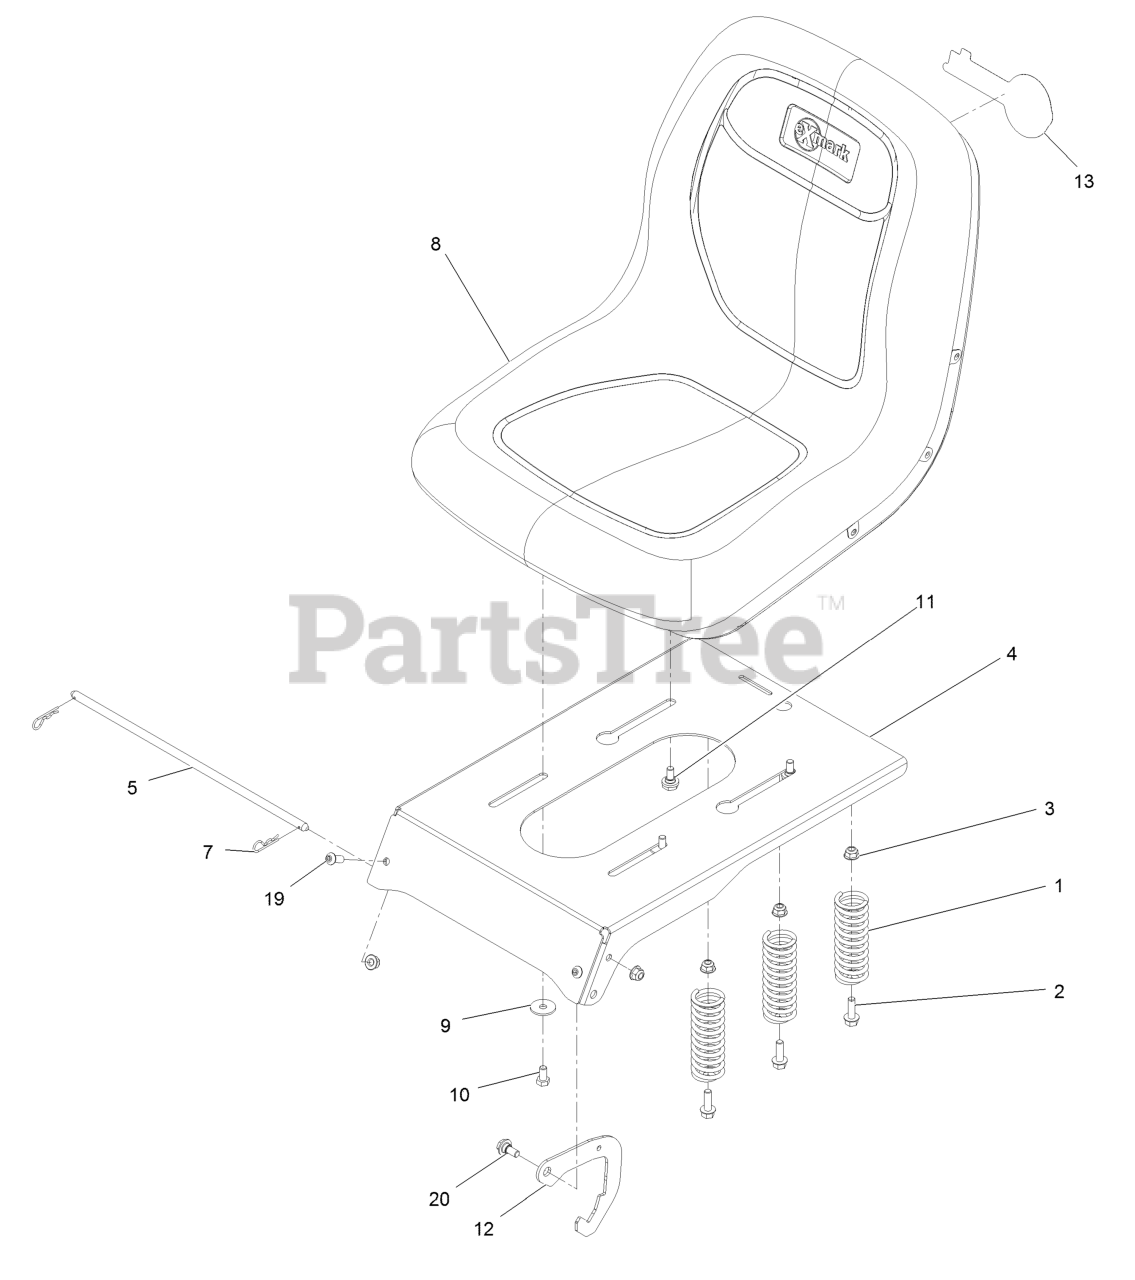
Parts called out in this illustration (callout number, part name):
1	Spring-Compression
2	Screw-HH Flg 5/16-18 X 1
3	Nut-Nyloc 5/16-18 Flg
5	Rod-Pivot, Narrow
7	Pin-Cotter
8	Seat-18 In
9	Washer-Pivot
10	Screw-HH 5/16-18 X 5/8
11	Screw-Shoulder 5/16-18 X 5/8
12	Latch-Seat
13	Decal, Exmark Logo
19	Screw-Button Head 5/16-18 X 3/4
20	Screw-Shoulder
